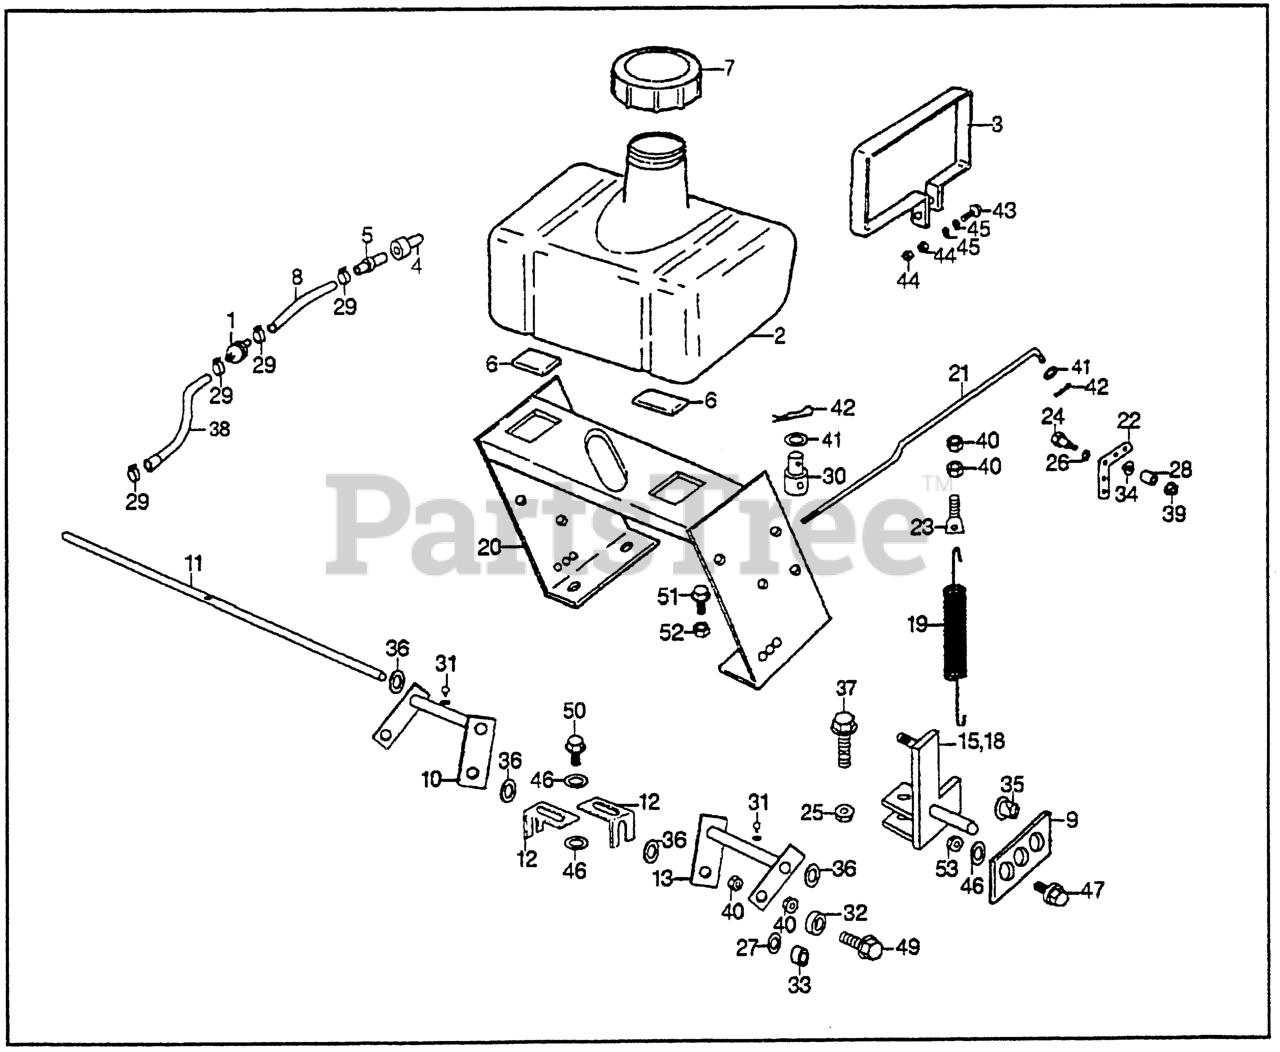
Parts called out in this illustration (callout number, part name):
1	FILTER, FUEL
2	TANK, FUEL (4.2)
3	STRAP, FUEL TANK
4	JOINT, CONNECTOR FUEL
5	PIPE, FUEL
6	PAD, FUEL TANK
7	CAP, FUEL TANK
8	LINE, FUEL (24")
9	SUPPORT, PUMP SHAFT
10	ARM, R. SPEED STOP
11	SHAFT, CROSS
12	SPACER, CROSS SHAFT
13	ARM, L. SPEED STOP
15	ARM, R. PUMP
18	ARM, L. PUMP
19	SPRING, PUMP ARM
20	SUPPORT, HANDLE
21	ROD B, P.T.O.
22	BELLCRANK (3")
23	BOLT, SPRING ADJUSTER
24	BOLT, SHOULDER (3/8"-16)
25	NUT, SELF-LOCK (5MM)
26	WASHER, BELLEVILLE (1/2") Use up to Frame SN 1000677.
27	WASHER (5/16X9/16X1/8) (NOT AVAILABLE)
28	SPACER (1/2")
29	CLAMP, FUEL LINE
30	PIN, CLEVIS (5/16")
31	NIPPLE, GREASE
32	BEARING, PUMP STOP
33	COLLAR, BEARING
34	BUSHING, SNAP
35	BUSHING, PUMP ARM
36	BUSHING (5/8")
37	BOLT, HEX. (5X25)
38	BULK HOSE, FUEL (4.5X1000) (4.5X130)
